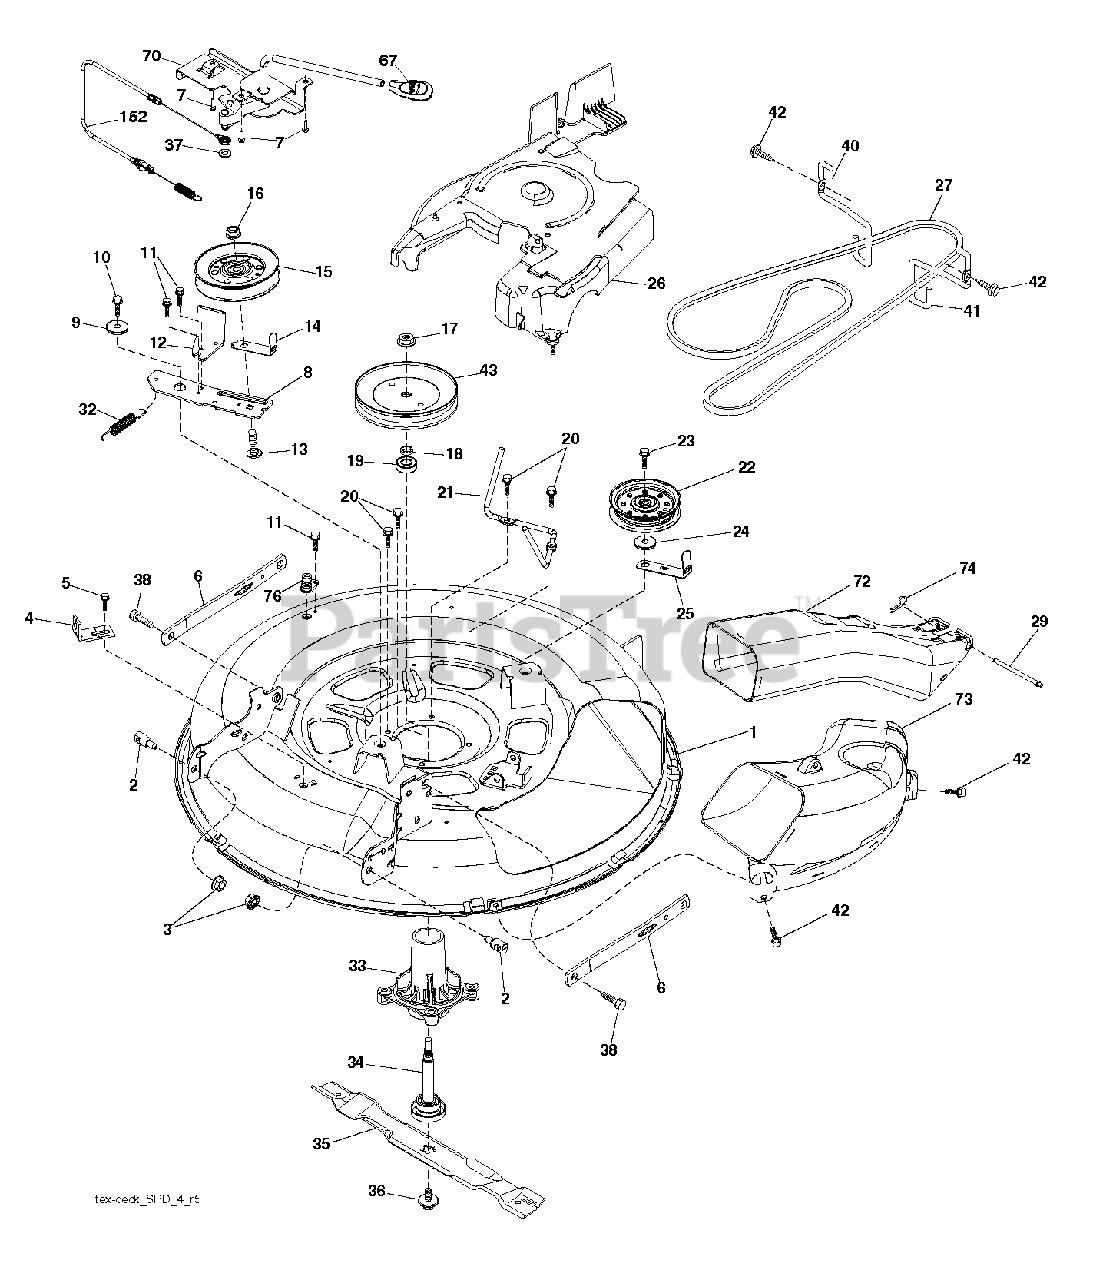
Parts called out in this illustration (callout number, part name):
2	STUD.FASTNER.W/ANTI-ROTATE
3	NUT LOCK HEX FLANGE 5/16-18
5	BOLT.5/16HEX.WHS.HD
6	ARMS.SUSP.MOWER.REAR.SRD
7	SCREW.#10 X 0.750.BOS THREAD
9	SPACER.RETAINER
10	SCREW 3/8-16X1
11	SCREW.1/4-20X5/8
12	ARM BRAKE MOWER RH
13	BOLT.3/8-16X1.50
14	KEEPER, BELT IDLER
15	PULLEY.IDLER.4.25
16	NUT LOCK FLG 3/8-16 UNC
17	NUT.FLANGE.LOCK.TOP
18	WASHER.SPACER.MANDREL
20	SCREW, WASHER HEAD
22	PULLEY.IDLER.FLAT.46.PR.DR.
23	SCREW LT
27	V-BELT.DRIVE.MOWER.30"
32	SPRING RETURN
33	HOUSING MANDREL
34	SHAFT.ASM.MDRL.N/GREASE.38
35	BLADE.MOWER.BAGGING.30"
36	BOLT.WASHER.ASM.7/16-2
38	BOLT.SHOULDER
42	SCREW, 3/8-16X3/4
43	PULLEY, MANDREL 6.5 PD
67	HANDLE.CLUTCH.CABLE.LT
70	CLUTCH.ASM.MANUAL.LT.PRED
74	RETAINER-SPRNG RB
76	PORT.WASHOUT
152	CLUTCH CABLE
